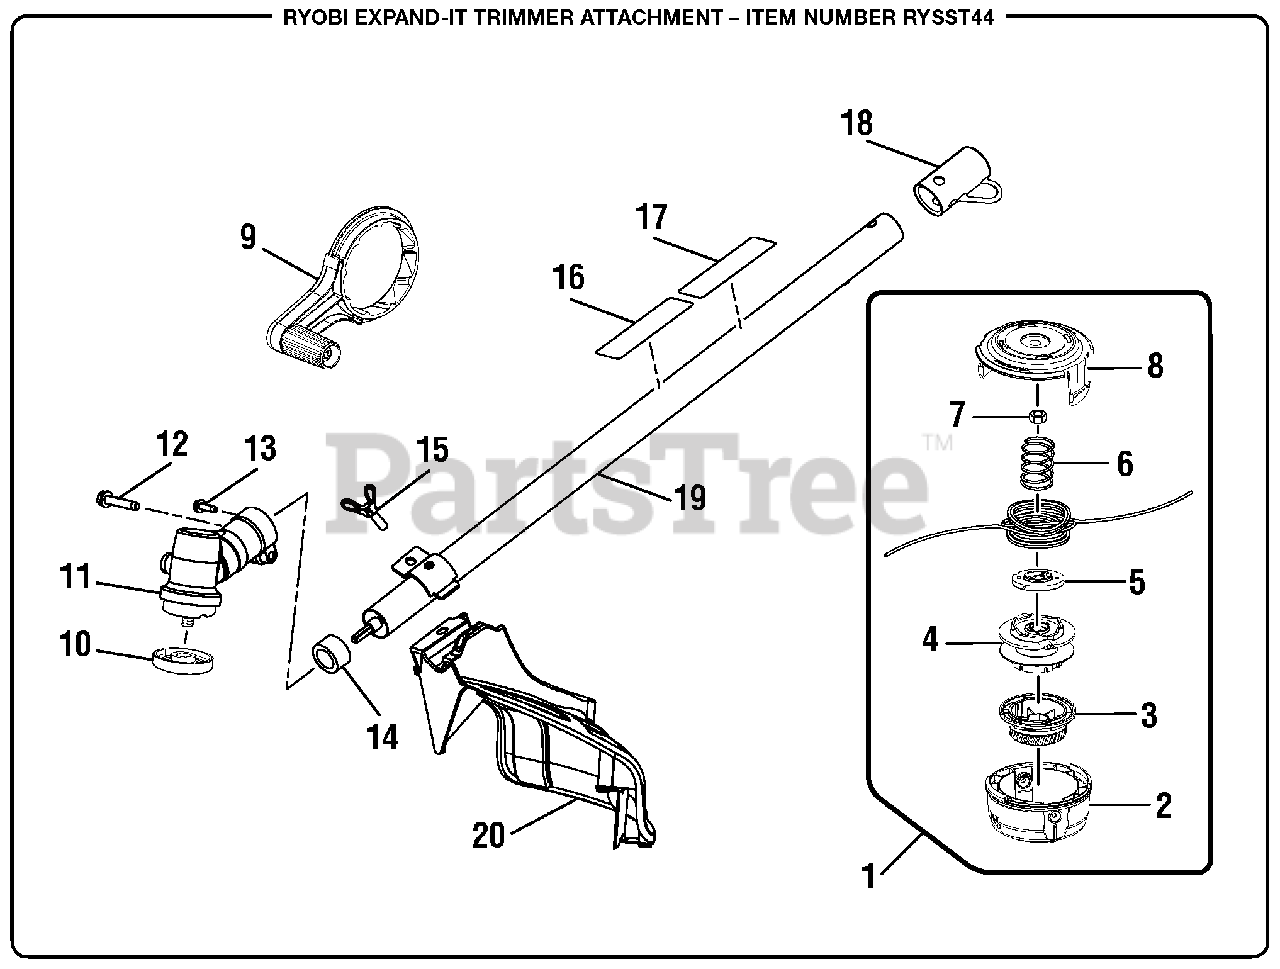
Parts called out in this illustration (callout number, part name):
1	Trimmer Head Assembly (.095)
2	Lower Housing
3	Bump Knob (Green)
5	String Guide
6	Compression Spring
7	Hex Nut (M8, L.H. Thread)
8	Upper Housing
9	Crank Handle Assembly
10	Flanged Washer
11	Gear Case Assembly
12	Screw (1/4-20 x 1-1/4 in., Hex Washer Hd. S.T.)
13	Screw (10-24 x 5/8 in., Hex Washer Hd. S.T.)
15	Wing Screw (1/4-20 x 7/8 in.)
16	Expand-it Label
17	Warning Icon Label
18	Storage Hanger Cap
19	Straight Shaft Assembly
20	Grass Deflector Assembly
